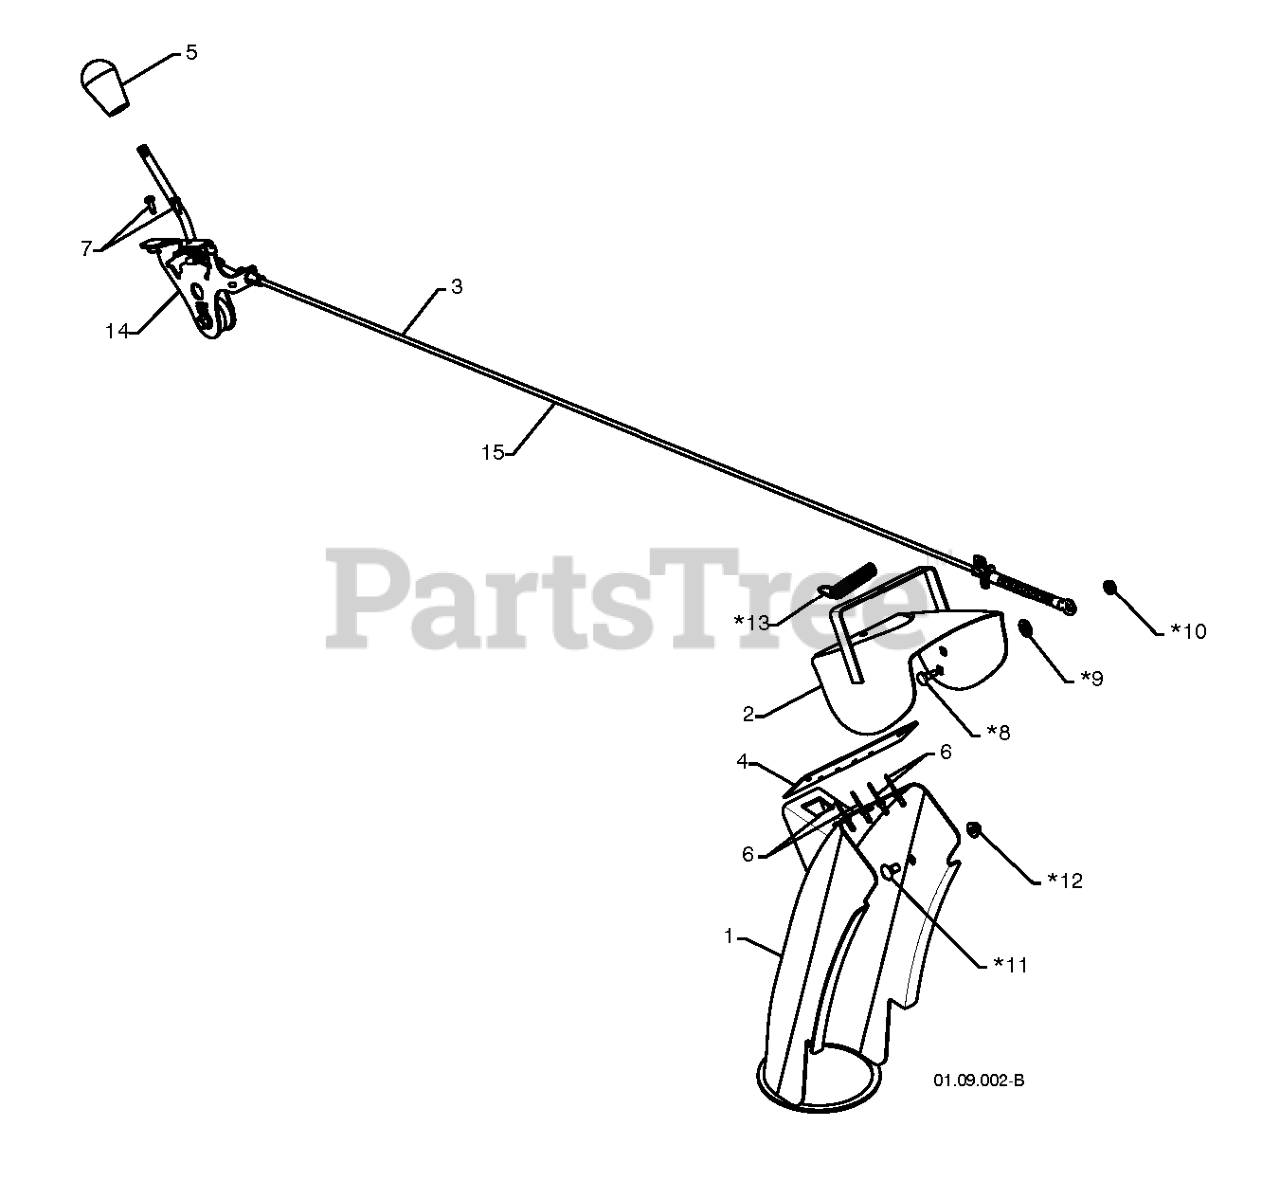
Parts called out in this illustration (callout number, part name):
1	CHUTE ASSEMBLY
2	DEFLECTOR.WELDMENT.PNT.ORANGE
3	RP.CONTROL.ASM.DEFLECTOR.SNOW
4	SEAL.DEFLECTOR
5	KNOB LEVER, BLACK
6	RIVET BLIND
7	SCREW #10-24 X 5/8
14	RP CNTRL.HEAD.ASSEM.DEFLECTOR
15	RB SERVICE.CHUTE.DEF.CBL.BLK
